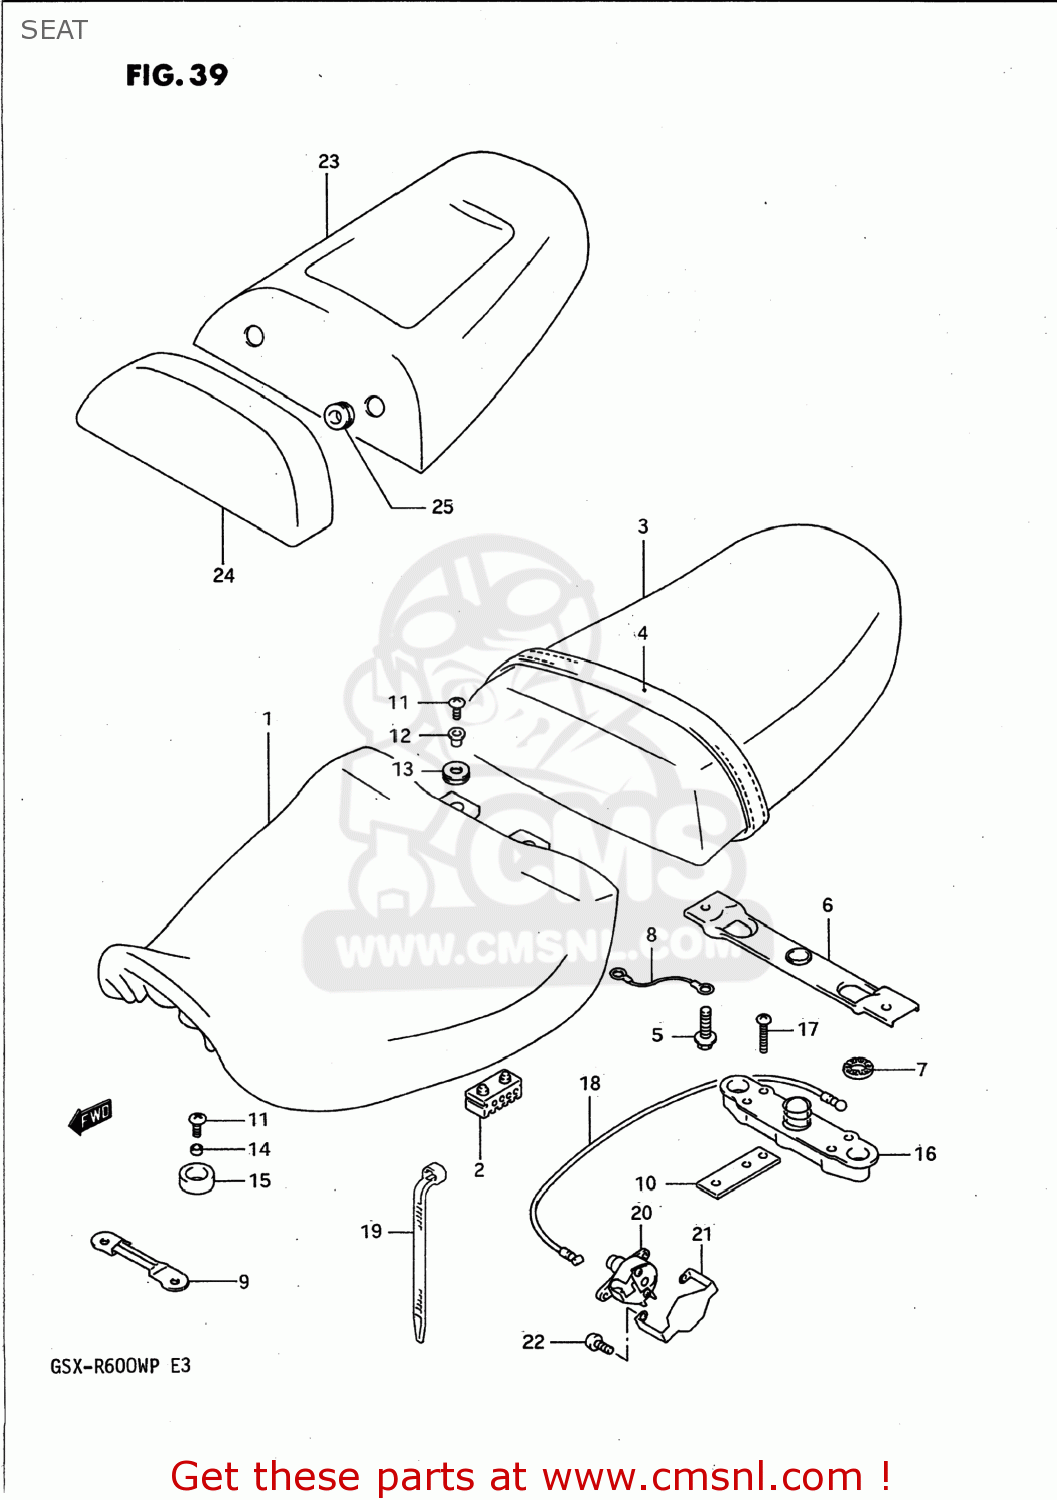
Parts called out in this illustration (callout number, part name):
1	SEAT ASSY
2	CUSHION,SEAT(40X20X15)
3	SEAT ASSEMBLY,PILLION
4	BAND,SEAT
5	BOLT 6X20
6	STRIKER,SEAT LOCK
7	CUSHION
8	CABLE, PILLION SEAT
9	PLATE,SEAT FR HOOK
10	BRACKET COMP,SEAT SUPPORT
11	SCREW
12	WASHER
13	CUSHION
14	SPACER (6.8X10X4.7)
15	CUSHION,TAIL COVER UPR
16	LOCK ASSY,SEAT STRIKER
17	SCREW
18	CABLE,SEAT LOCK
19	CLAMP(L:165)
20	LOCK SET,SEAT
21	PLATE,SEAT LOCK GUARD
22	SCREW(6X12)
23	BOX SET,SEAT TAIL
24	BACKREST COMP,SEAT
25	CUSHION
